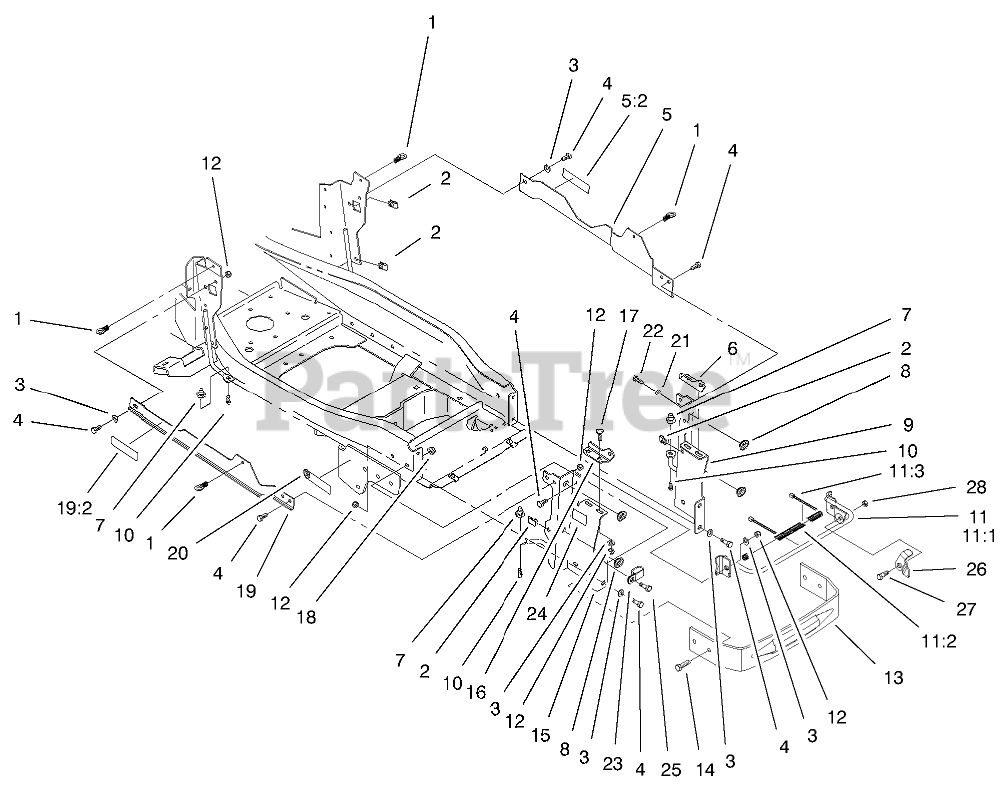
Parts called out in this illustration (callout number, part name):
1	LATCH ASM
3	WASHER-PLAIN
4	SCREW-HH
5	ASM-Support w/Decal (Only On: 73590)
5	ASM-Support w/Decal (Only On: 73552)
5:2	Decal-Warning (Only On: 73552)
5:2	Decal-Warning (Only On: 73590)
6	BRACKET-HINGE, LOWER LH
7	MOUNT-SIDEPANEL
8	GROMMET
9	SUPPORT-HOOD, LH
10	SCREW-PLASTITE
11	SUPPORT-HOOD
11:1	Hood Support Brace W.a.
11:2	COVER-BRACE
11:3	TIE-CABLE
12	NUT-LOCK, NI
13	BUMPER-FRAME
14	SCREW-HH
15	SUPPORT-HOOD, RH
16	BRACKET-HINGE, LOWER RH
17	SCREW-CARR
18	NUT-LOCK, NI
19	ASM Support/Decal (Only On: 73590)
19	ASM-Support/Decal (Only On: 73552)
19:2	Decal-Warning (Only On: 73590)
19:2	Decal-Warning (Only On: 73552)
20	DECAL-ATTACH A-MATIC
21	Washer-Flat (Only On: 73590)
22	Screw-Selftap (Only On: 73590)
23	CLAMP-TUBE
24	DECAL-SURFACE, HOT
25	SCREW-HH
26	LEVER-PROP, HOOD
27	BOLT-SHOULDER
28	NUT-LOCK, NI
